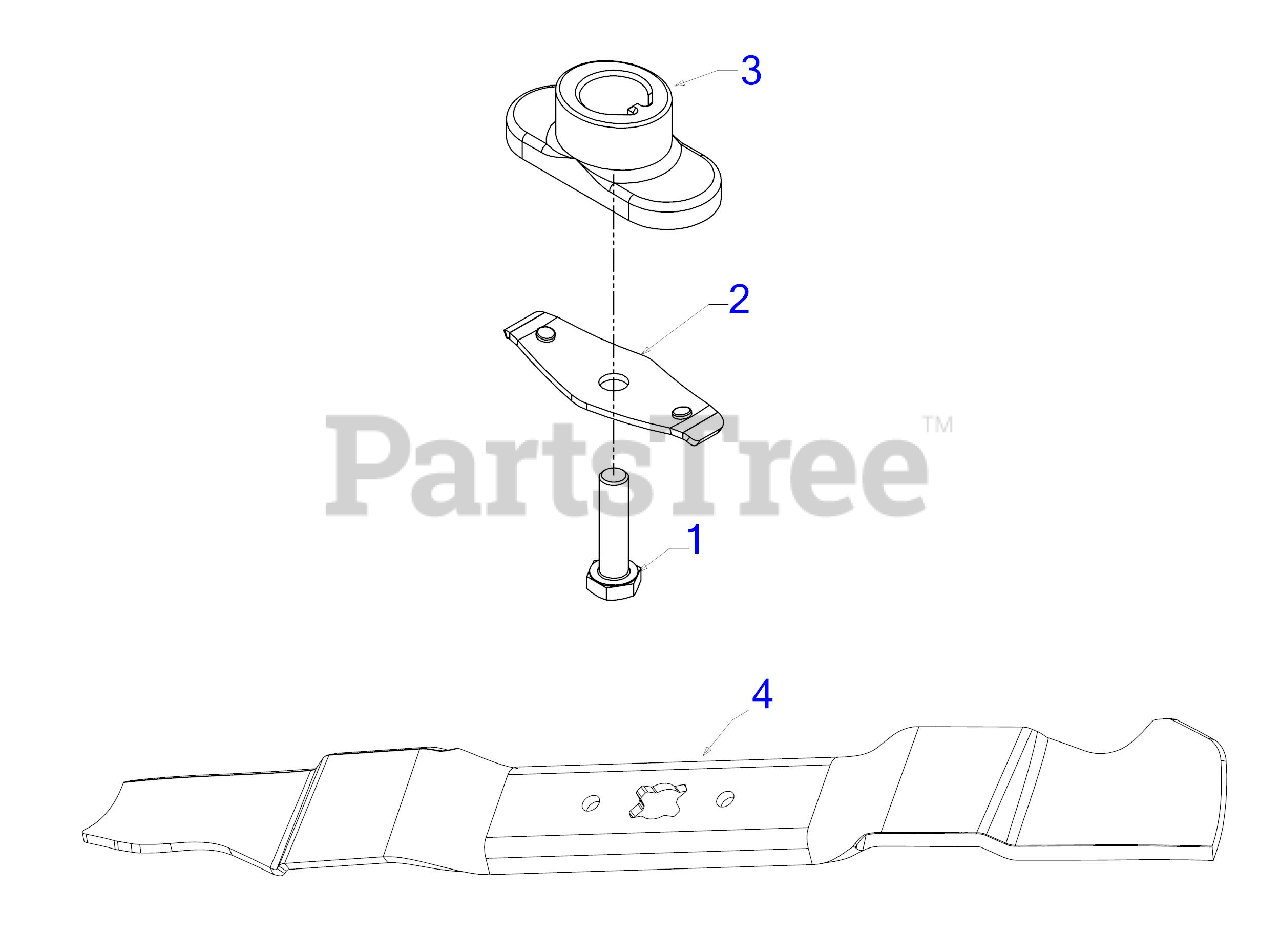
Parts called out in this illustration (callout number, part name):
1	SCREW 3/8-24 x 1.50 GR8
2	BLADE BELL SUPPORT
3	BLADE ADAPTER-W/STAR
4	21" MULCHING BLADE (2-IN-1)
